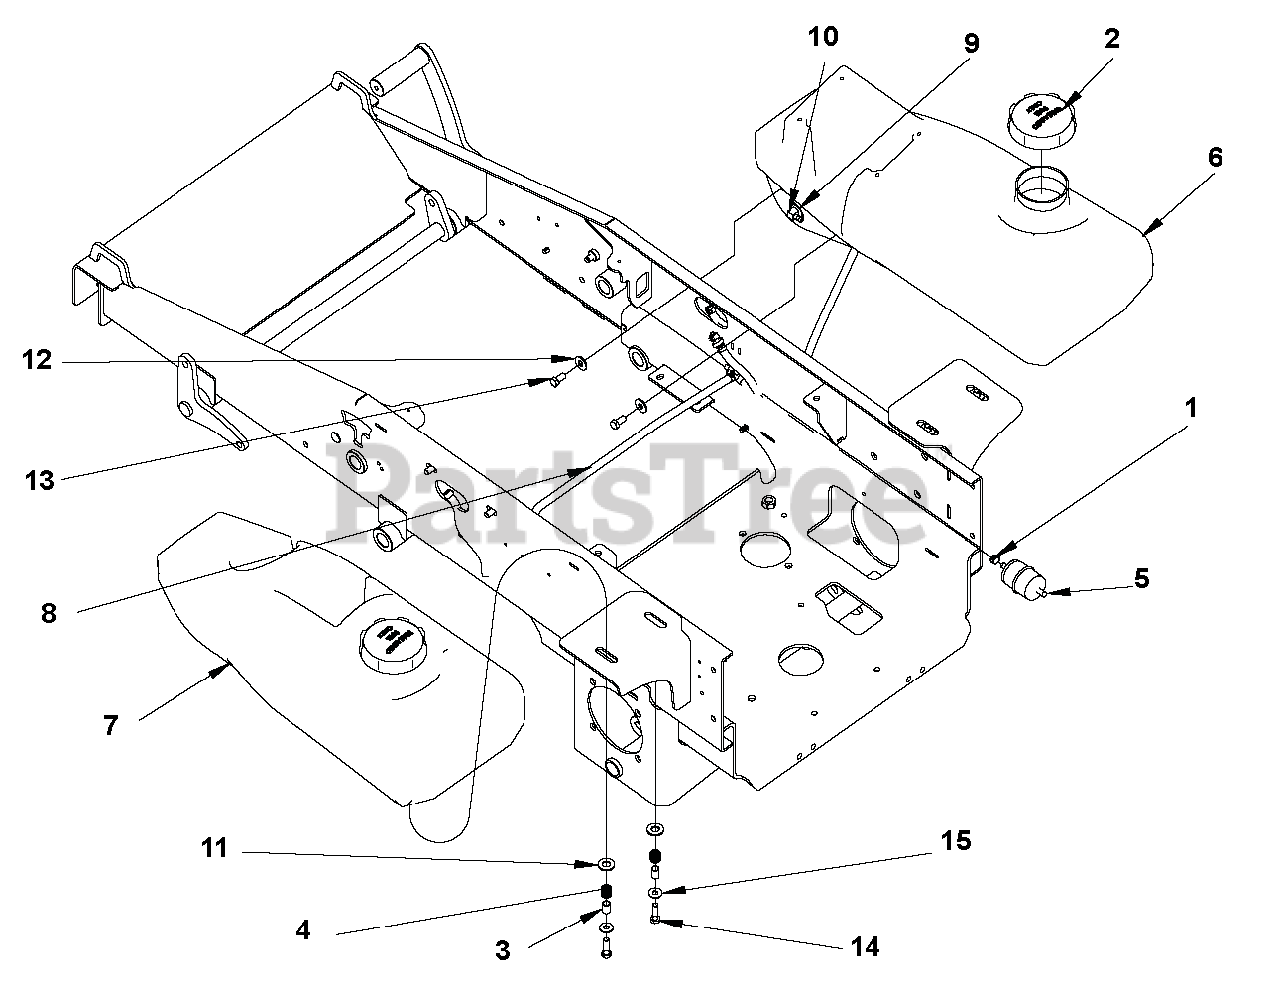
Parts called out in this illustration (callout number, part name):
1	CLAMP, HOSE - 1/2" SPRING
2	CAP, FUEL S/O
3	SPACER, GAS TANK ATTACHMENT
4	SPRING, COM .660 X .067 X .625
5	FUEL FILTER - KAWASAKI
6	TANK, RH MIDMOUNT BLANK W/CAP
7	TANK, LH MIDMOUNT BLANK W/CAP
8	ASSY, FUEL LINE W/CHECKVALVES
9	GROMMET, RUBBER TANK S/O
10	FTG, 90 1/4HOSE X 1/2HOSE S/O
11	WASHER, .500X1.00X.105 FLAT Y
12	@WSHR-FL-STL.438X1.00X.083 YWZ
13	BOLT, 3/8-16X.750 HEX 5 Y
14	BOLT, 3/8-16X1.25 HEX 5 Y
15	@WSHR-FL-STL.38X.875X.083 YWZC
